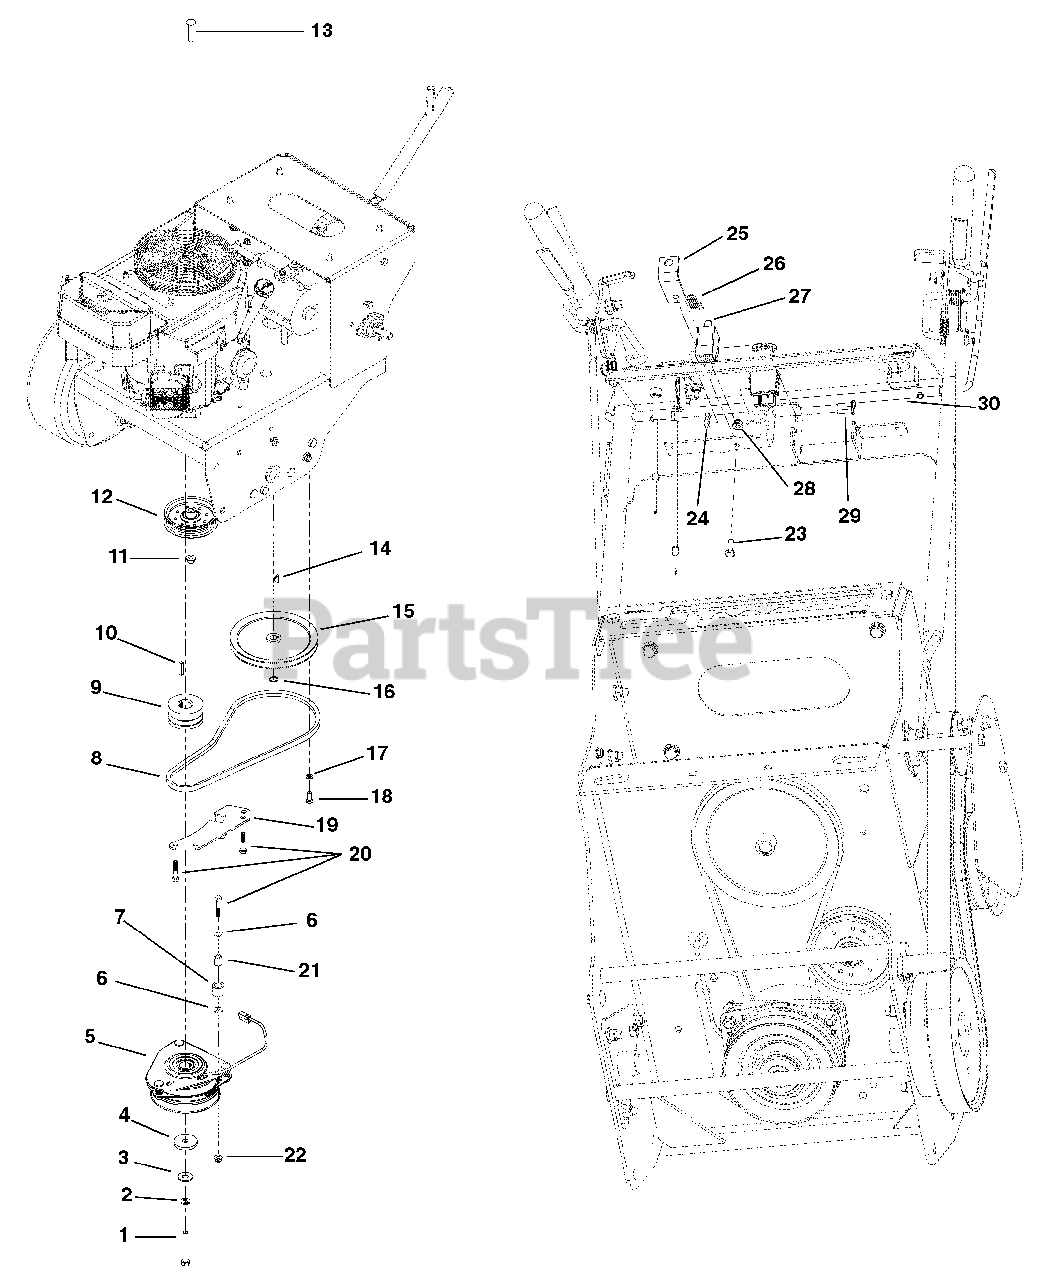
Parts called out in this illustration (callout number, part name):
1	Bolt, .44-20 x 3.00 Hex Grade 5
2	Washer, .438 Medium Spring Lock
3	Washer, Flat-Steel .50 x 1.25 x .083
4	Washer, Flat-Steel .469 x 2.00 x .25
5	Clutch Assembly, Ogura
6	Washer, Flat-Steel .531 x 1.062 x .095
7	Bumper, Rubber .62 x 1.0 x .88
8	Belt, HA 40.60 Raw Laminated
9	Sheave,1.002 ID x 3.222 PIN
10	Key, Square .248 x 1.25 x .248
11	Nut, Nyloc Flange, .38-16
12	Pulley, V-Belt 4.00 x .379 w/BRG
13	Bolt, Round Head Square Neck .38-16 x 2.00
14	Key, Woodruff .19 x .75 HRD #9
15	Pulley, V 7.50 x .626
16	Ring, Retaining-External .579 x .035
17	Washer, .313 Medium Spring Lock
18	Bolt, .313-18 x .750 Hex Grade 5
19	Weldment, Clutch Stop
20	Bolt, .313-18 x 1.75 Hex Grade 5
21	Bushing, S .407 x .625 x .813 ST
22	Nut, Nyloc Flange, .31-18
23	Bolt, .25-20 x .750 Hex Grade 5
24	Locknut, 10-24 Nyloc
25	Bracket, Brake Link
26	Spring, Tension .047 x .438 x 1.45
27	Switch, Interlock
28	Nut, .25-20 Nyloc Flange
29	Screw, Machine 10-24 x .75 Hex Washer Head
30	Weldment, Pivot Tube
